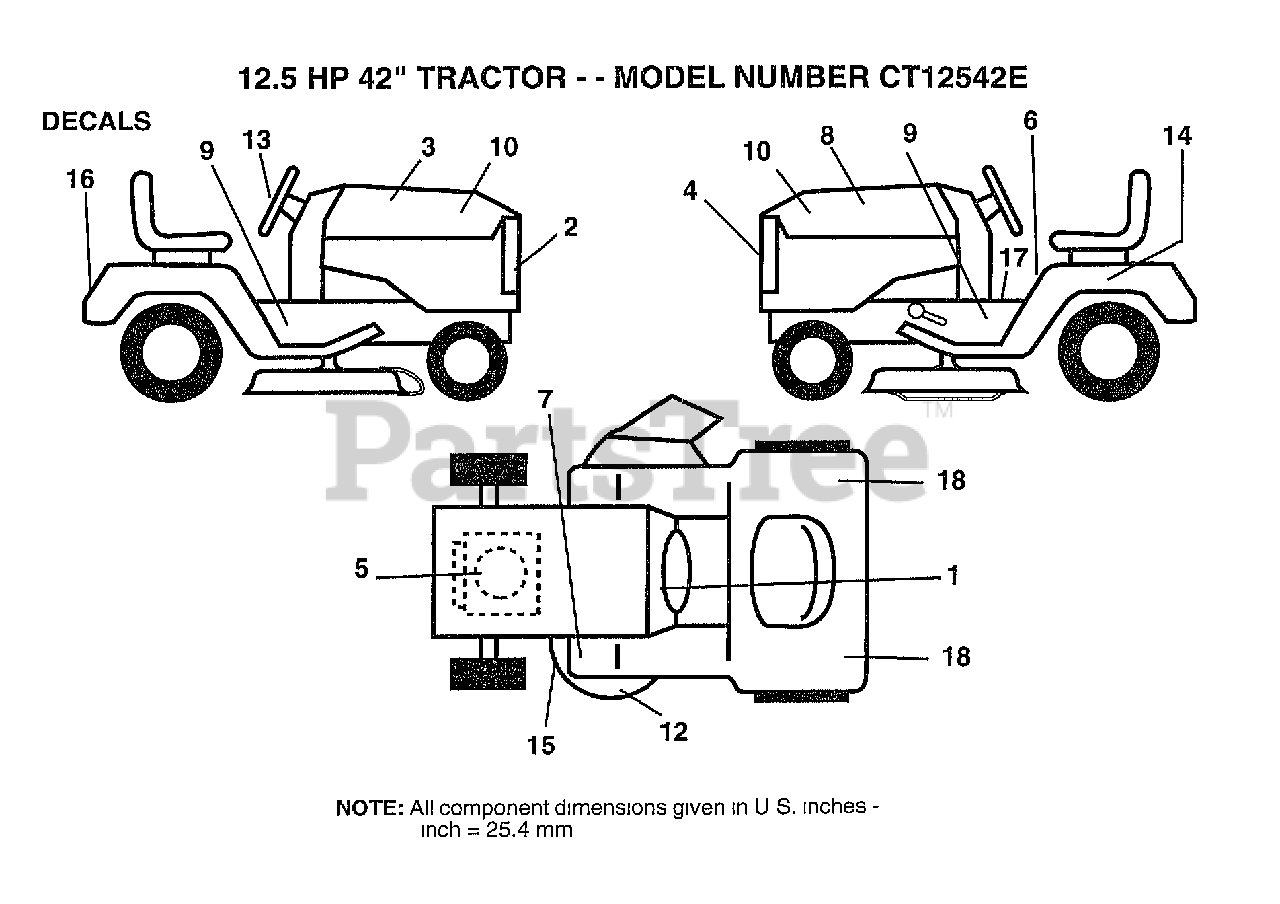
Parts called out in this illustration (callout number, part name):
1	DECAL.DASH.INST.
2	DECAL.GRILLE
3	DECAL HD RH RALLY
6	DECAL
8	DECAL HD LH RALLY
9	CHASSIS DECAL
10	"DECAL, HP HOOD"
13	DECAL INST STRWHL
14	DECAL
15	DECAL.V.BELT
16	DECAL.FENDER
17	DECAL BRAK PARK
18	REFLECTOR-TAIL YT
